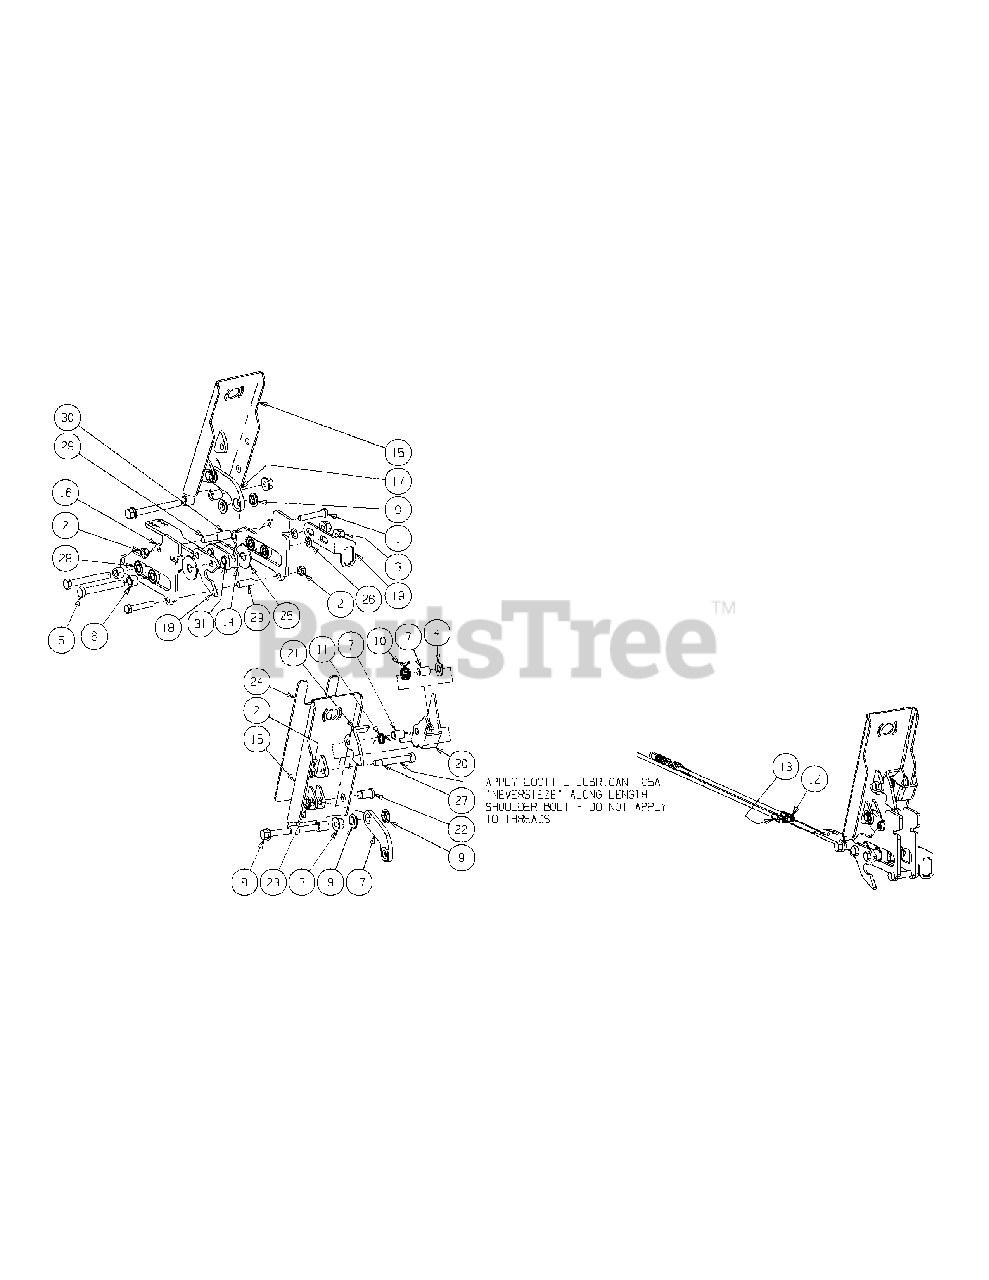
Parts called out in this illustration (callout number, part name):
1	HHCS, 5/16-18 x 1-3/4
2	Lock Nut, 5/16-18, Center
3	Flange Lock Hex Nut, 3/8-16
4	Washer, 3/8, SS
5	HHCS, 3/8-16 x 3.00
6	Spacer, .385 ID x .625 OD x .458
7	Spacer, .380 x .500 x .667
8	HHCS, 3/8-16 x 3.50
9	Flange Bearing, .502 x .875 x .180
10	Torsion Spring
11	Torsion Spring
12	Brake Cable, LH
13	Brake Cable, RH
14	Brake Carriage Assembly
15	Pedal Assembly, Brake
16	Roller Guide Brake Bracket
17	Brake Control Link
18	Lockout Control Plate
19	Brake Switch Mounting Bracket
20	Park Engage Bracket
21	Brake Bracket
22	Pin, .500 x .804 LG
23	E-Ring for .500 Dia. Shaft
24	Grip, Brake
25	Washer, .531 ID x 1.50 OD x .08
26	Washer, .39 ID x .62 OD x .03
27	Shoulder Screw, .375 x 2.00 x 5/16-18
28	Flange Bearing .375 ID x .875 OD
29	Spacer, .319 x .375 x 1.056
30	Spacer, .384 x .500 x 1.00
31	Spacer, .38 ID x .50 OD x .955
